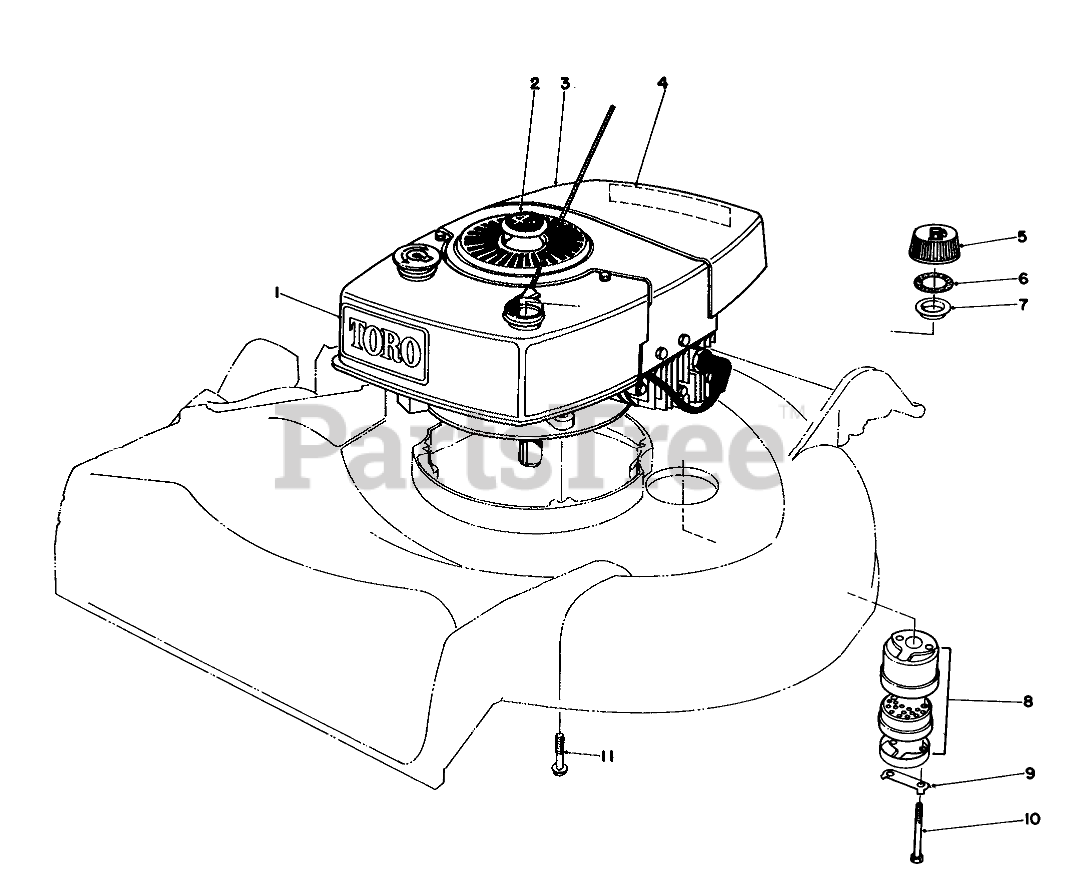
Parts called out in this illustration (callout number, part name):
1	Decal Tow
2	PLUG BUTTON
3	Engine
4	Decal-Maintenance
5	Gas Cap Assembly (Incl. Ref. #6 & 7)
6	GASKET
7	GAS CAP BAFFLE
8	Muffler Assembly (Incl. Ref. #9 & 10)
9	CLIP - LOCKING
10	SCREW-HH
11	3/8-16 X 2-3/4 CAPSCR
